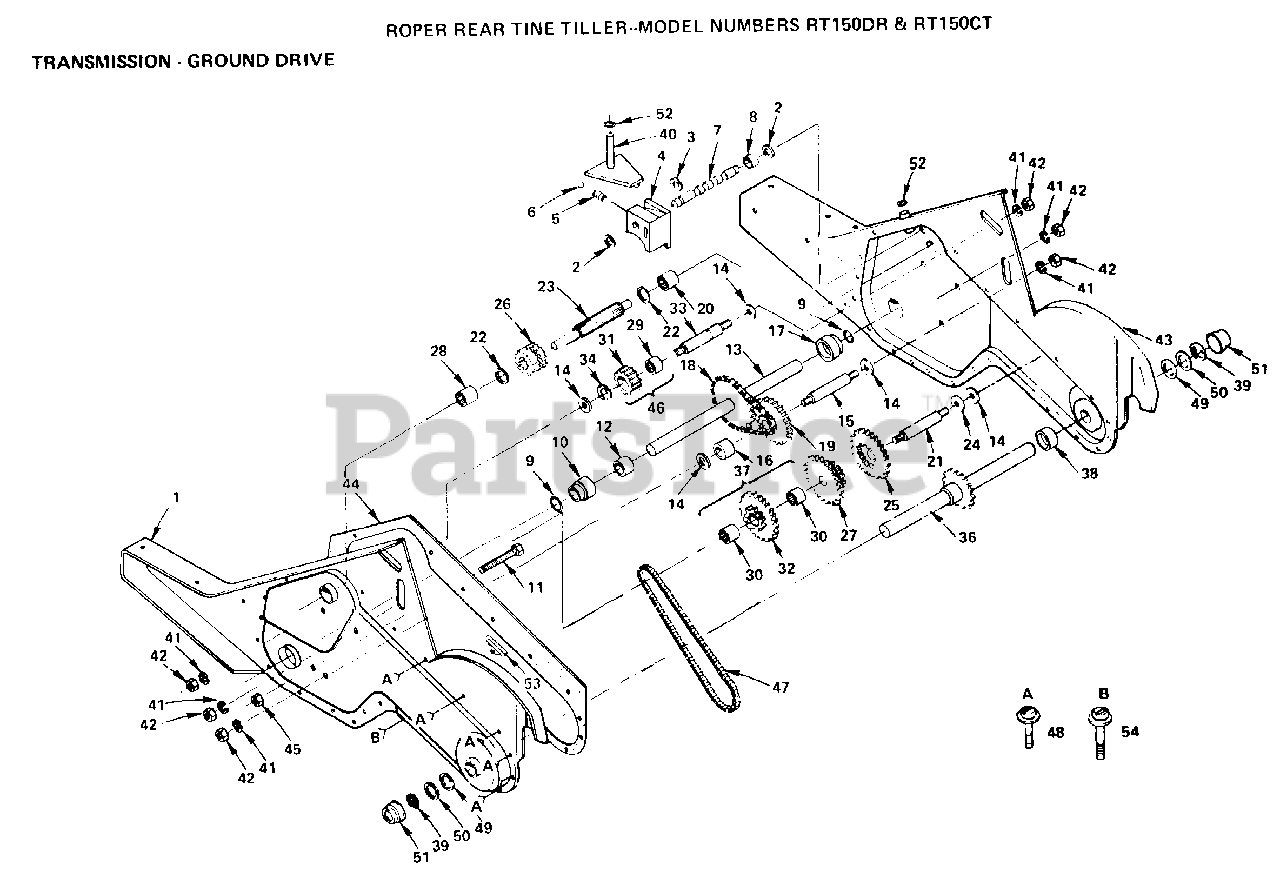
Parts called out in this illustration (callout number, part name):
2	WASHER SEAL CRT
3	KLIP RING
4	SHIFT FORK TI
5	SPRING-SHIFT CRT
7	SHAFT SHIFT CRT
8	SPACER SPLIT CRT
9	O RING CRT
10	"CRT, BEARING"
11	SCRW WHIZ LOK CRT
12	BUSHING TI
14	WASHER
15	SHFT 2ND RED. CRT
16	SPACER TI
18	CHAIN CRT
19	SPRCKT 8 GEAR CRT
20	"TI, BEARING"
21	REDUCTION SHFT TI
22	"T, BEARING"
23	SHAFT-INPUT CRT
24	BRNG RACE
25	GEAR TI
26	PINION-INPUT CRT
27	GEAR TI
28	NEEDLE BRNG LT
29	NEEDLE BEARING TI
30	BEARING
31	GEAR-REV IDLR CRT
33	SHAFT CRT
34	KLIP RING
36	SHAFT ASSY TI
38	SPACER TI
39	RING SPIRAL CRT
40	ARM ASSY CRT
41	LOCKWASHER
42	NUT.ASF.HEX.7/16
44	GASKET TI
45	NUT.HEX.5/16-18
46	GEAR ASSY CRT
47	CHAIN.50 LINK TI
48	SCREW CRT
51	CUP.FORMED.
52	O-RING TI
